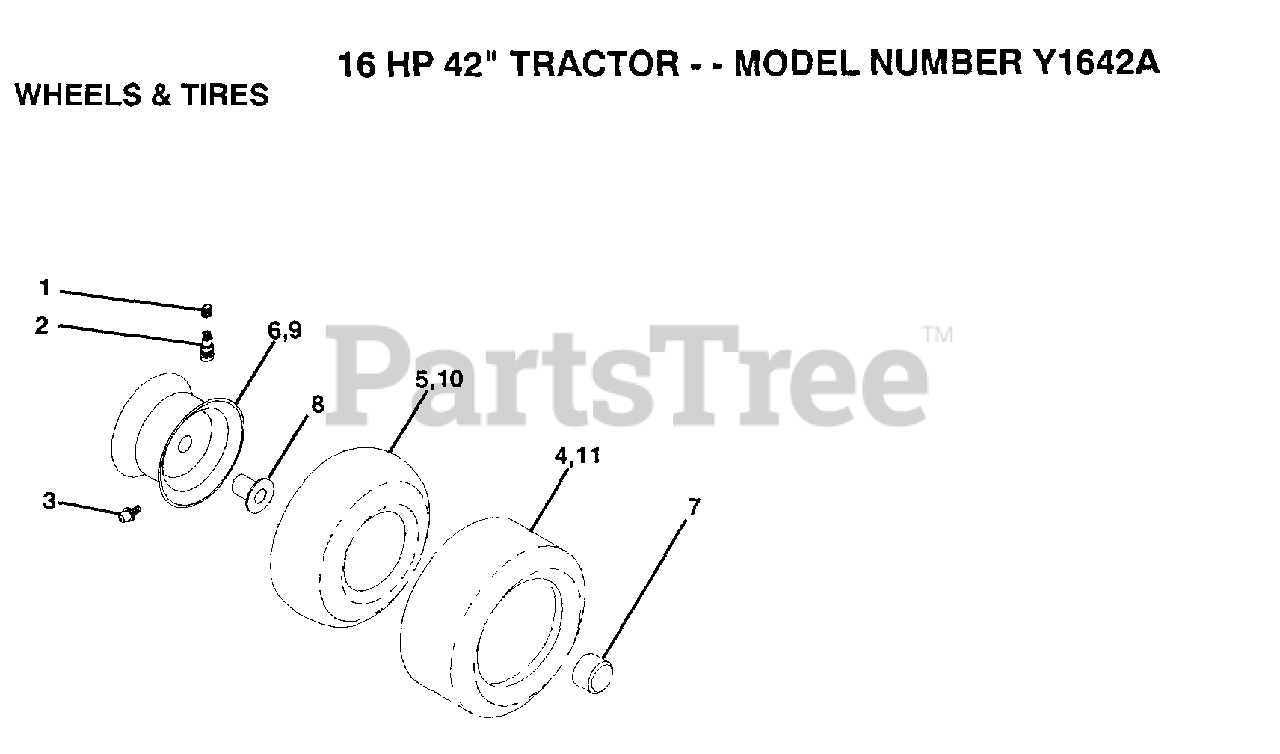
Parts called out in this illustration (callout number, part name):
1	VALVE CAP
2	VALVE STEM LT
3	FITTING LT
5	TUBE.18X9.5-8
7	HUB CAP
8	"FLANGE, BEARING"
10	TUBE.5.3/4.5/6
